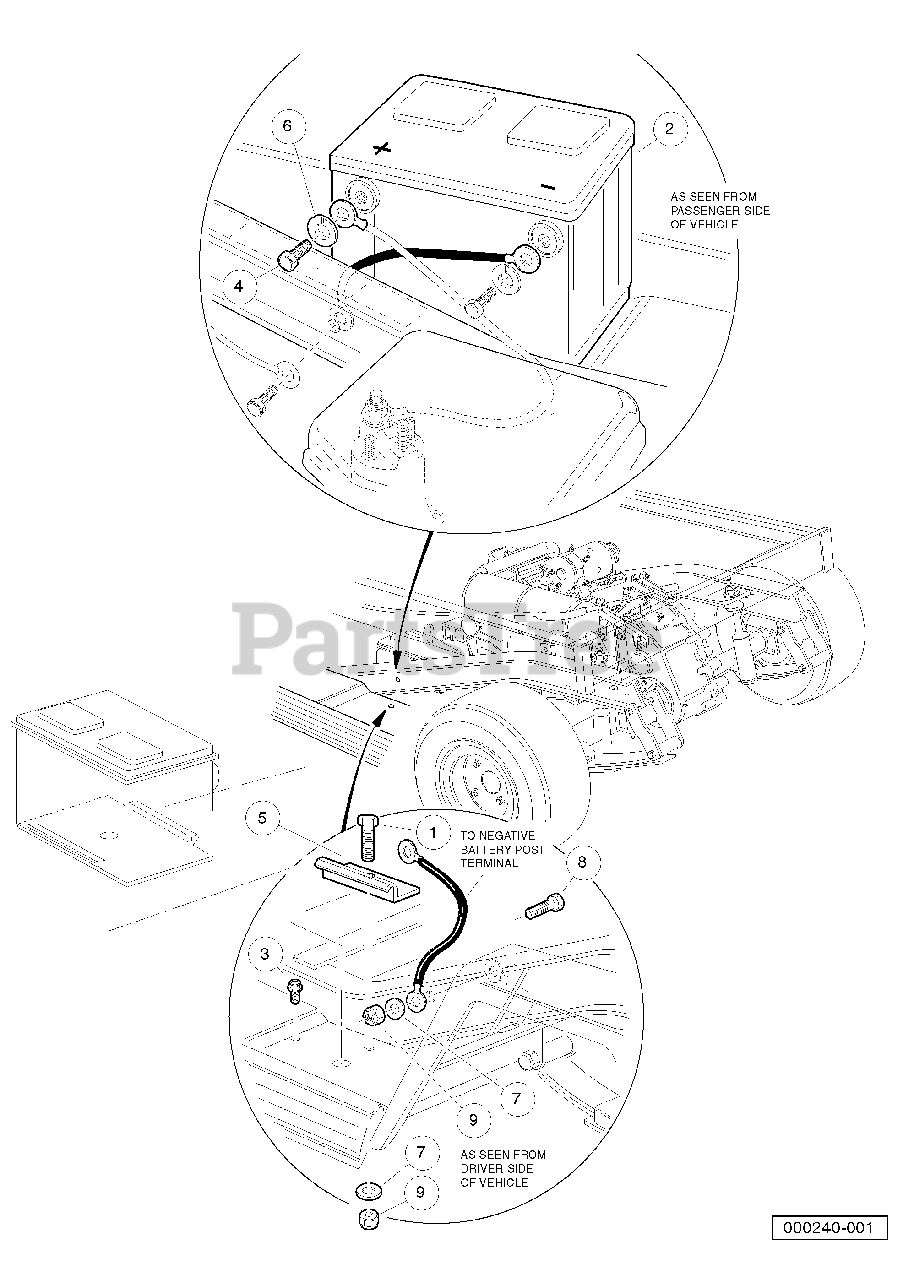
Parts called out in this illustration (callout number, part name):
1	Screw, 5/16-18 X 1.00 Hex Cap
2	Battery, 12-Volt
3	Screw, 5/16-18 X 0.75 Thread-Forming
4	Screw, 3/8-16 X 0.50 Stainless Steel Hex-Head
5	Clamp, Battery
6	Lockwasher, 3/8 Stainless Stl
7	Washer, 5/16 Type A Flat
8	Screw, 5/16-18 X 0.75 Hex-Head Cap
9	Locknut, 5/16-18 Nylon Insert
